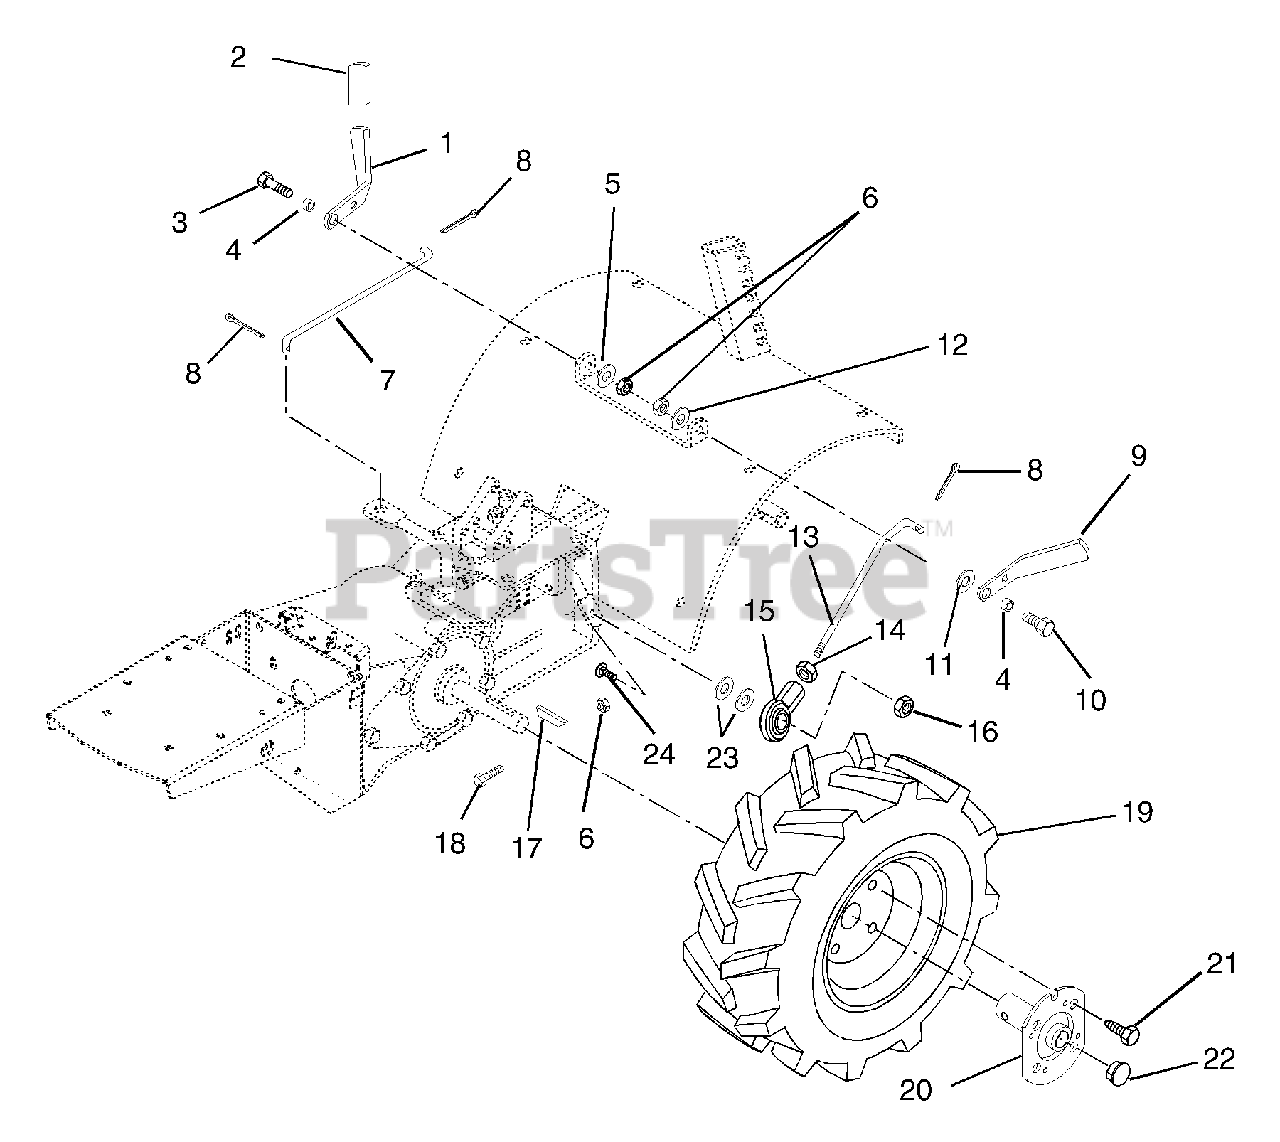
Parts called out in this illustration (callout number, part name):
1	DRIVE CLUTCH HANDLE
3	@BLT-HEX .31-18X1.25 GR5 YWZC
4	SPACER BUSHING .5 X .32 X .21
5	@WSHR-FL-STL.38X.875X.083 YWZC
6	@NUT-LK-CTR .31-18 YWZC
7	DRIVE CLUTCH ROD
8	@PIN-CTR .09X.75 EXTPRSQCT YWZ
9	TILLER CLUTCH HANDLE
10	@BLT-HEX .31-18X.75 GR5 YWZC
11	SPACER .344X1.000X.375
12	WSHR-FL-STL .347X1.254X.048YWZ
13	TILLER CLUTCH ROD
14	NUT-HEX .312-24 YWZC
15	ROD END, FEMALE 5/16
16	@NUT-LK-CTR .31-18 YWZC
17	KEY-FTHR .25X1.875X.25 SAE
18	@BLT-HEX .31-18X2.00 GR5 YWZC
19	T/WHL ASSY 4.80-8
20	WHEEL HUB
21	SCR-TAP .500-20X.62 HH YWZC
22	HOLE PLUG 1.00"
23	@WSHR-FL-STL.344X.688X.065YWZC
24	@BLT-RDHDSQNK .31-18X1.00 G5YZ
